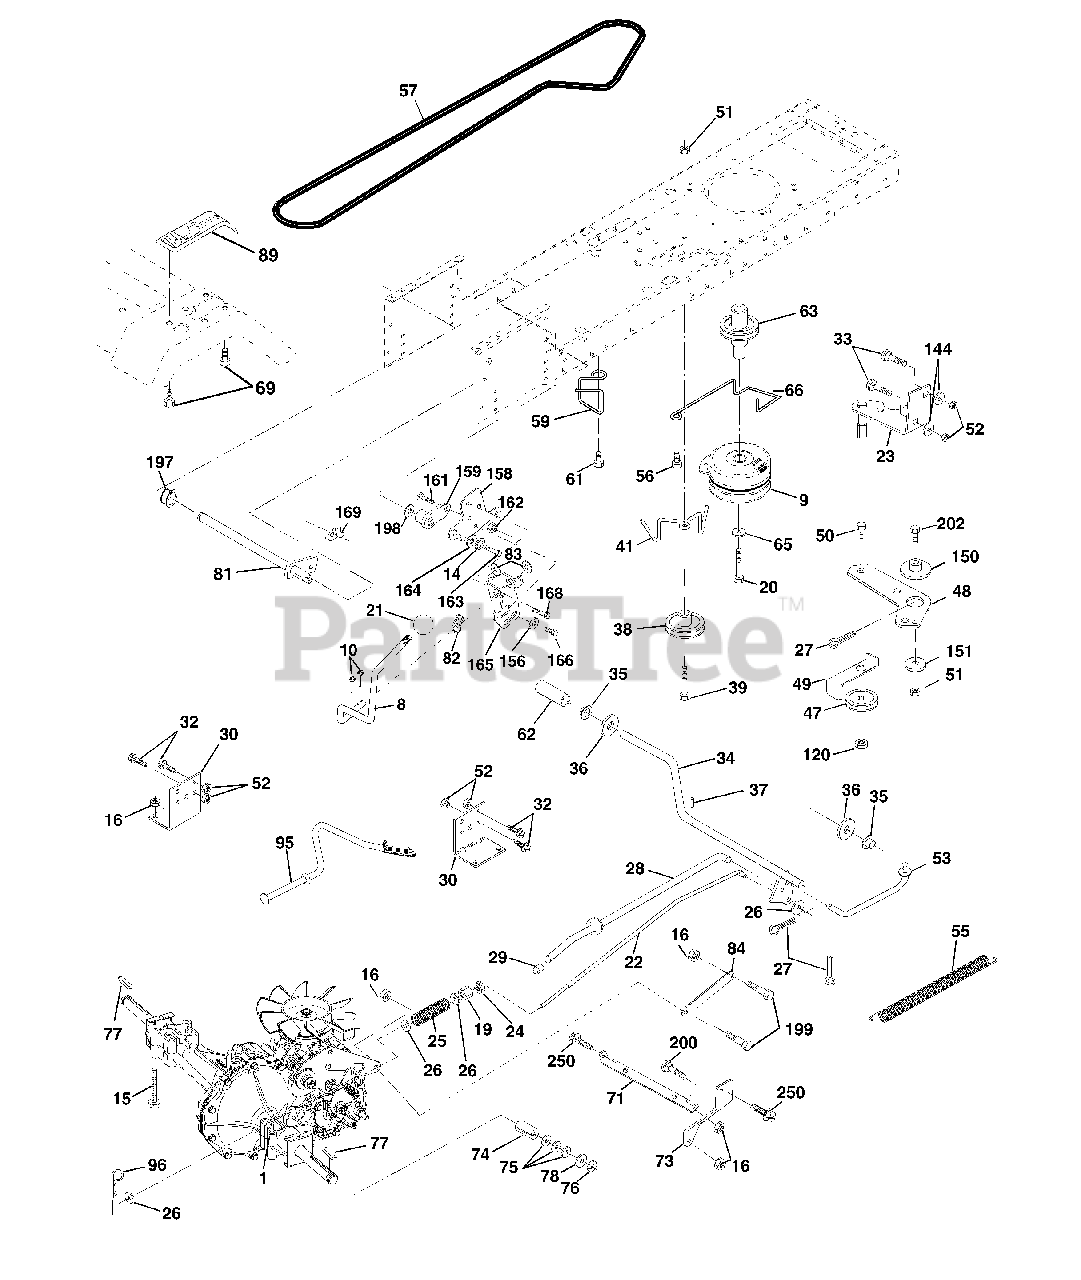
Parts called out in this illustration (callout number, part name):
8	Rod Shift Fender Adjust LT
9	Clutch Electric
10	Pin Cotter 1/8 x 1 CAD
14	Washer Lock Hvy Helical
15	Bolt Hex 5/16-18 Gr. 5
16	Nut Lock Hex W/Ins. 5/16-18 Unc P
19	Nut Lock Hex W/Ins 3/8-16 Unc
20	Bolt, Hex 7/16-20 x 4-1/4 Ga. 5
21	Knob Deluxe 1/2-13 UNC BLK/BLK
22	Rod, Brake Hydro
23	Bracket Asm. Anti-Rot EVX
24	Nut Hex Jam 3/8-16 UNC
25	Spring, Brake Rod
26	Washer
27	Pin Cotter 1/8 x 3/4 CAD.
28	Rod, Parking Brake
29	Cap,Parking Brake
30	Bracket, Transaxle
32	Bolt Hex Hd 5/16-18 Unc x 3/4
33	Bolt Carriage 5/16-18 UNC x 3/4
34	Shaft, Foot Pedal
35	Bearing, Nylon
37	Pin, Roll
38	Pulley, Idler, Composite
39	Bolt
41	Keeper, Belt Idler
47	Pulley, Idler, V-Groove Plastic
48	Bellcrank Clutch Grnd Drv Stl
49	Retainer, Belt Style Spring
50	Bolt Hex Hd 3/8-16 Unc x 1-1/2
52	Nut Crown Lock 5/16-18
53	Link, Clutch
55	Spring, Return, Clutch
56	Screw 3/8-16 x 1 1/4
57	V-Belt, Ground Drive
59	Keeper, Center Span
61	Screw
62	Cover, Pedal
63	Pulley, Engine
65	Washer Lock Hvy HLCL Spr 7/16
66	Keeper Belt Engine
69	Screw Hex Wsh Hi-Lo 1/4-1/2 Unc
71	Strap Torque Lh
73	Strap Torque Rh
74	Spacer, Axle
75	Washer 25/32 x 1-1/4 x 16
77	Key, Square
78	Washer 25/32 x 1-5/8 x 16
81	Shaft Asm Cross Tapered
82	Spring Torsion
83	Washer 17/32 x 3/4 x 16 Ga.
84	Link Transaxle
89	Console, Hydro
95	Control Asm. Bypass Hydro
96	Retainer Spring 1" Zinc/Cad
120	Nut Lock Flg. 3/8-16
144	Washer 11/32 x 5/8 x 16 Ga.
150	Bushing Bellcrank Grd Drive
151	Washer 13/32 x 2 x 10 Ga.
156	Washer Srrted 5/16 ID X 1 X .125
158	Bracket Shift Mount
159	Hub Tapered Flange Shift LT
161	Bolt Rdhd Sqnk 1/4-20 x 3/4 Gr. 5
162	Nut Crownlock 1/4-20 Unc
163	Bolt Hex Fin 1/4-20 Unc x 1 Gr. 5
164	Washer 5/8 x .281 x 10 Ga.
165	Bracket Pivot Lever
166	Screw 5/16-18 x 5/8
168	Bolt Shoulder 5/16-18 x .561
169	Plate Fastening LT
197	Nyliner Snap-In 5/8" ID
198	Washer Nyl 7/8ID x .105 Hyd
199	Bolt Shoulder 5/16-18 Unc
200	Bolt Rdhd Sqnk 5/16-18 Unc x 1
250	Screw 3/8-16 x .75
